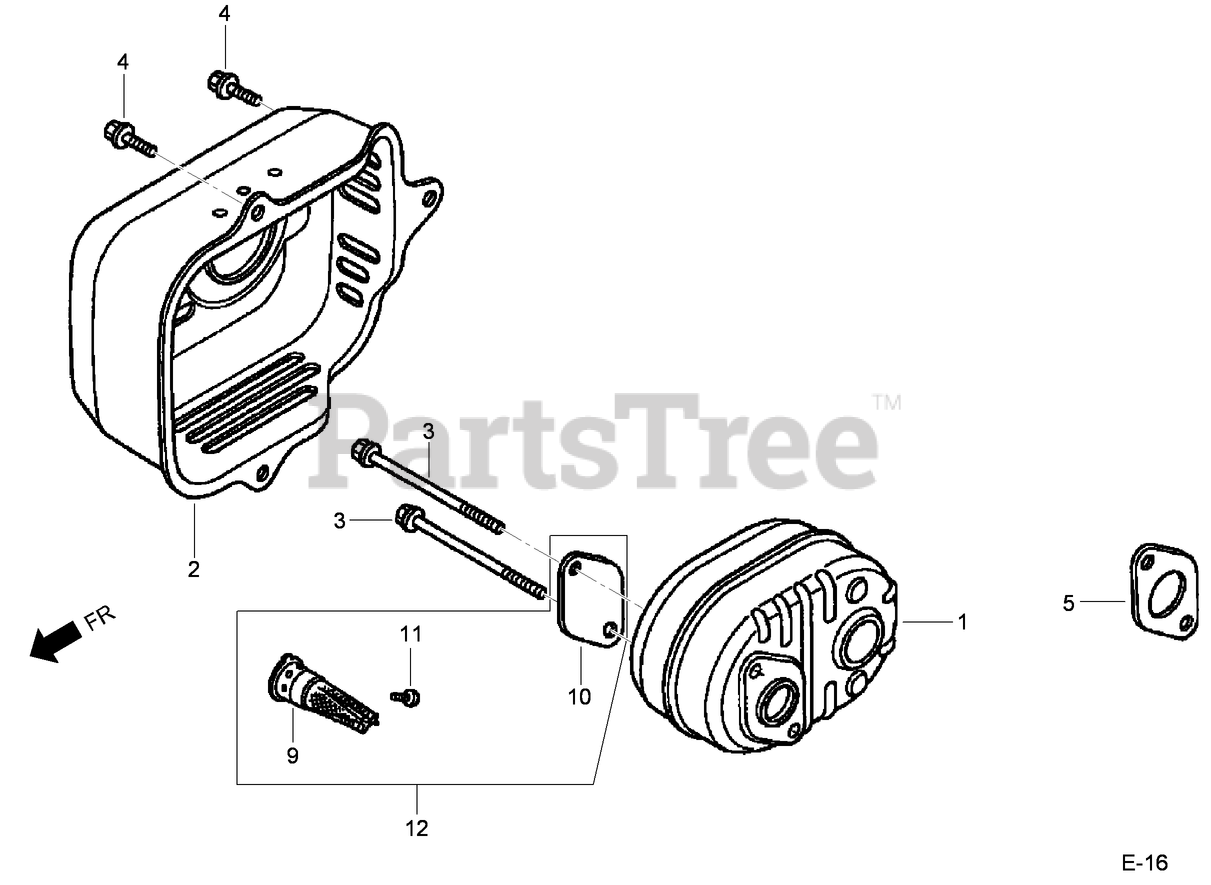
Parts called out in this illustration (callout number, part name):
1	MUFFLER
2	PROTECTOR-MUFFLER
3	BOLT-FLANGE (6X79) (C T200)
4	BOLT-FLANGE (6X12) (C T200)
5	GASKET-MUFFLER (Optional Equipment)
9	ARRESTER-SPARK (Optional Equipment)
10	PLATE-NUMBER, ARRESTER (Optional Equipment)
11	SCREW-TAPPING (4X6) (Optional Equipment)
12	SPARK ARRESTER KIT (Optional Equipment)
